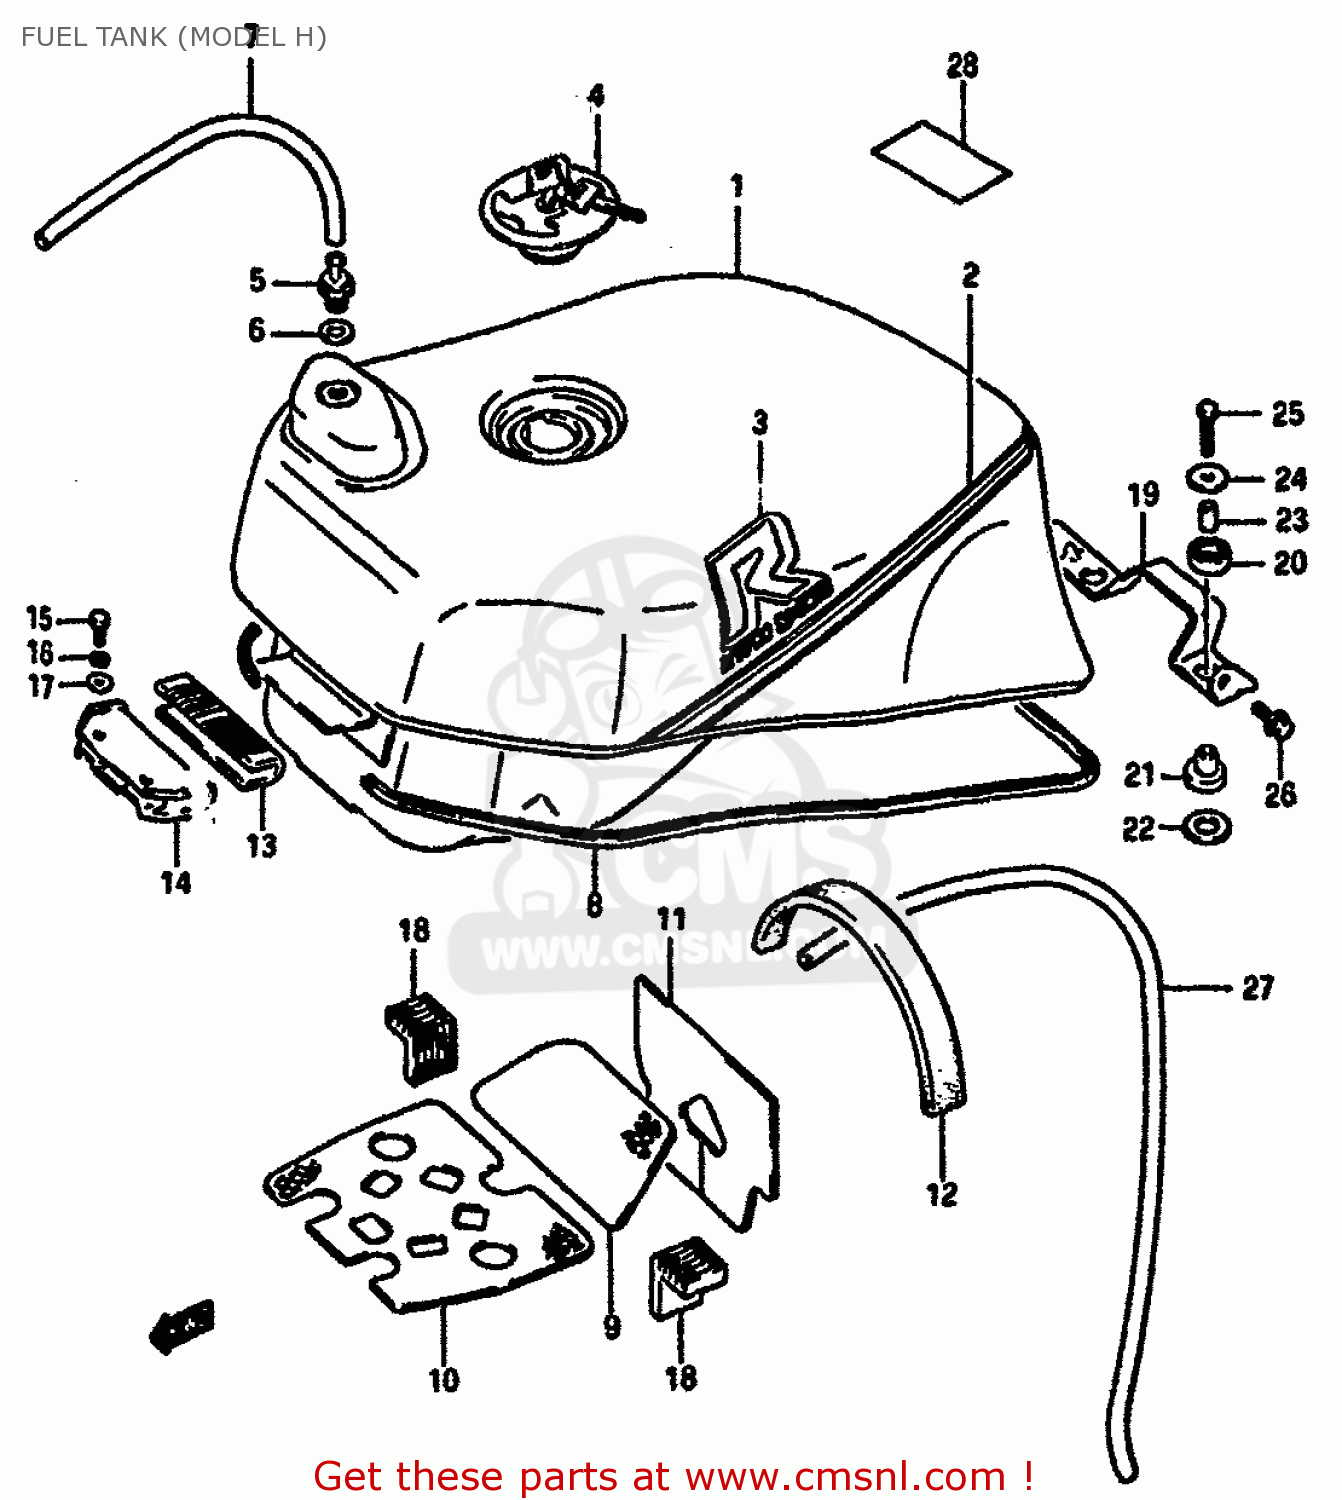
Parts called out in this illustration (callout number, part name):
1	TANK ASSY,FUEL
2	TAPE SET,FUEL TANK
3	EMBLEM
4	CAP SET,FUEL TANK
5	PLUG,FUEL TANK BREATHER
6	GASKET(12.5X20X2.5) (NAS)
7	HOSE
8	MOLDING,FUEL TANK
9	SHIELD,FUEL TANK HEAT
10	SHIELD,FUEL TANK HEAT
11	HEAT SHIELD,FUEL TANK
12	SHIELD,TANK & CLEANER
13	CUSHION,FUEL TANK FR
14	BRACKET,FUEL TANK FR
15	BOLT
16	WASHER,LOCK
17	WASHER
18	CUSHION,FUEL TANK SIDE
19	BRACKET,SEAT SUPPORT,FRONT
20	CUSHION
21	CUSHION
22	WASHER (12.5X24X1.6)
23	SPACER
24	WASHER (6.5X24X1.6)
25	BOLT ,6X35
26	SCREW(6X16)
27	HOSE,FUEL
28	LABEL,FUEL CAUTION
